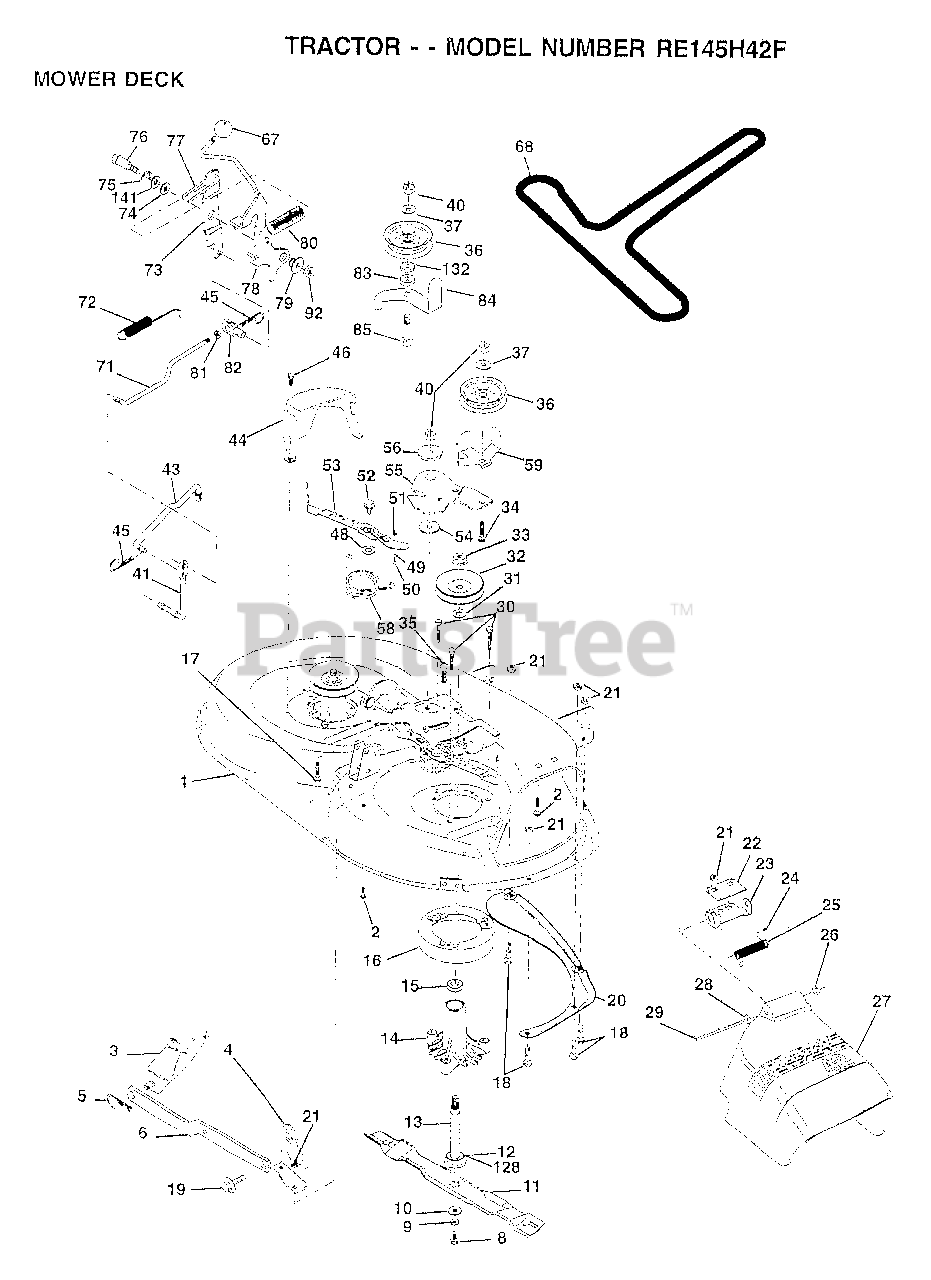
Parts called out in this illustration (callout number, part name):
1	"HOUSING ASSY.42"""
2	BOLT
3	BRKT ASM SWAY BAR
4	BRKT DECK SW BAR
8	BLADE BOLT
10	WASHER.HARD.BLADE
11	"BLADE.42"" HIPERF"
12	BEARING.BALL
14	HSG ASM MANDREL
15	BEARING
16	STRIPPER RND MWR
17	BOLT RDHD 3/8-16
18	BOLT
19	BOLT SHD 5/16-18
20	BAFFLE VORTEX 42
22	STIFFENER BRKT
23	DEFLECTOR BRKT
24	CAP-SLEEVE LT
25	SPRING TORSION
26	NUT PUSH M
27	DEFLECTOR.SHIELD
28	WASHER
29	HINGE ROD
30	"SCREW-THD ROLL,WA"
31	WASHER
32	PULLEY.MANDREL.42
34	BOLT
35	XMAS TREE FASTNER
36	FLAT IDLER PULLEY
37	WASHER
41	PIVOT ROD
43	ROD CLUTCH W/NIBS
44	GUARD MAND LH BLK
45	RETAINER M
46	SCREW.1/4-20X5/8
48	HARD SMALL WASHER
49	ROLLER ASM-CAM
50	SHOULDER BOLT
51	LOCKNUT
52	BOLT.SHLD.5/16-18
53	BRAKE PAD ARM ASM
54	HARDENED WASHER
55	ARM-IDLER
56	SPACER.RETAINER.MOWER
58	SPRING TORSN BRAK
59	GUARD IDLER TUV
67	KNOB.RD.7/16-14
68	BELT.V.T-PATH
71	ROD CLUTCH 38/42
72	RETURN SPRING
73	CLUTCH ARM SECOND
74	WASHER
75	RING
76	SHOULDER BOLT
77	SPRING KEEPER
78	LEVER.ASM.CLUTCH
79	BUSHING
80	SPRING.CLUTCH.MWR
81	NUT
82	TRUNION ADJ
83	WASHER
84	"KEEPER-BELT,FIXED"
85	BOLT
92	NUT
128	WASHER.FELT.
132	WASHER GT
141	WASHER .T
